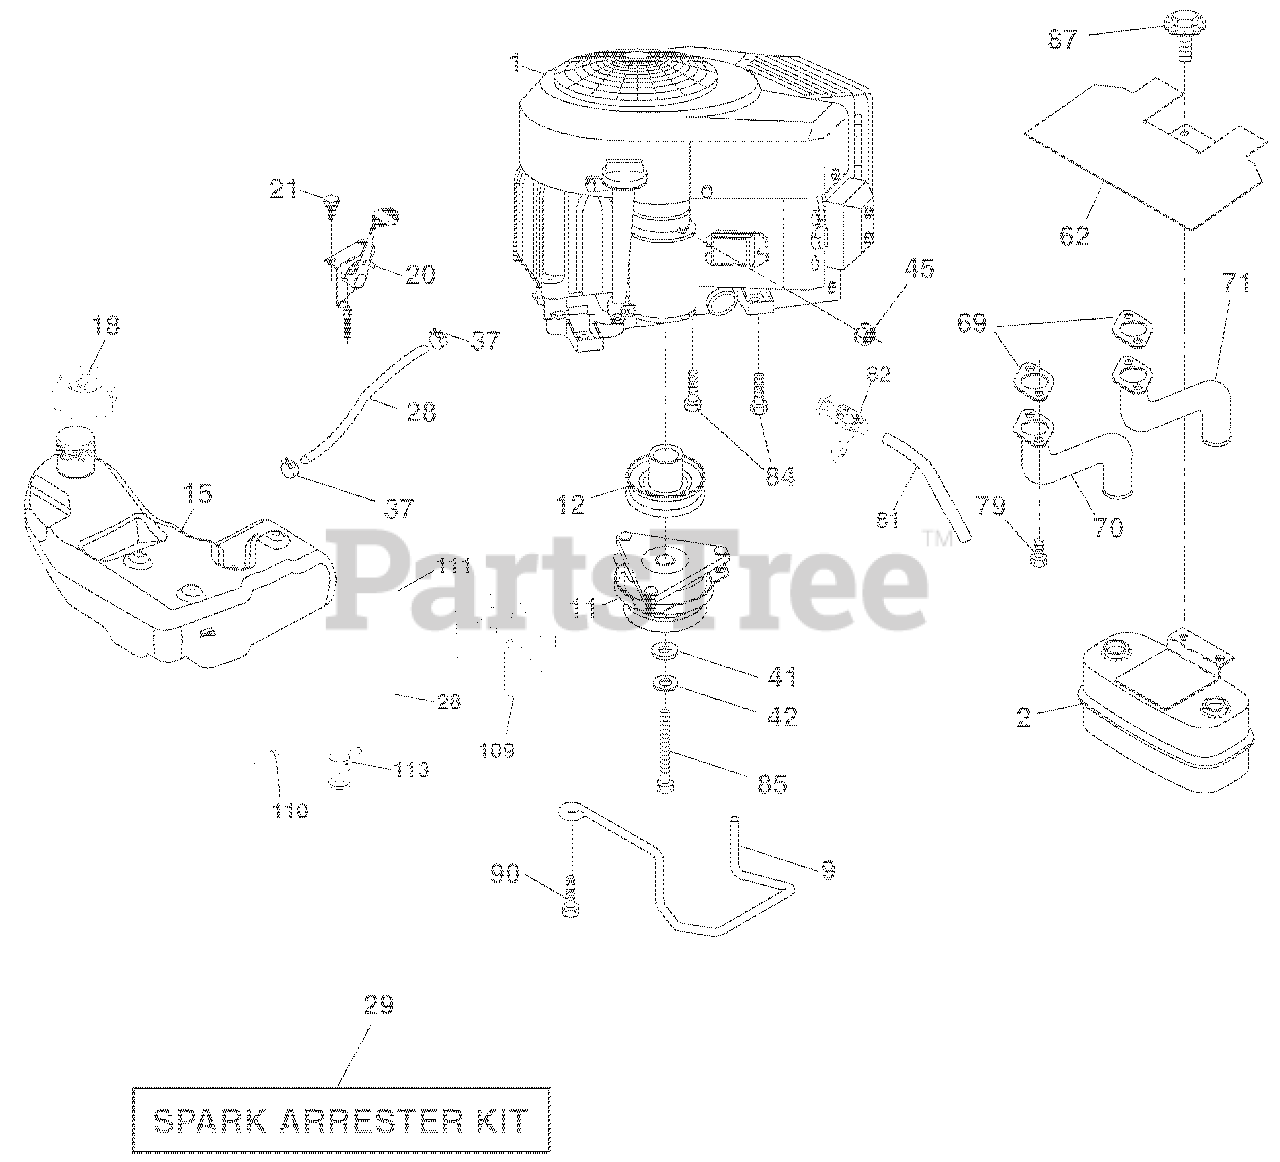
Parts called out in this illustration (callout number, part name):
1	ENGINE BRIGGS 407777-1569-G1
2	MUFFLER ASM.TWIN.LO-TONE
9	KEEPER.BELT.ENGINE.4.25"NSTG
11	CLUTCH.ELECTRIC.LT.1"CRANK
12	PULLEY.ENGINE.TUFFTORQE.1"CRK.
15	TANK.FUEL.ASM.3.00 GA.
18	CAP FUEL
20	CONTROL THROTTLE/CHOKE
28	LINE.FUEL.64"REAR.EMIS.CA.LP
29	KIT.SPARK ARRESTOR(392390 B&S)
37	CLAMP.HOSE.BLK.
41	WASHER.1-1/2 ODX15/32 IDX.250
42	WASHER.LOCK.HVY HLCL.SPR.7/16
45	Nut, Keps Hex 1/4-20 unc
62	SHIELD.HEAT.MUFFLER.
69	GASKET MUFFLER
70	EXHAUST TUBE LH
71	EXHAUST TUBE RH
79	SCREW SOCKET HEAD 5/16-18 X 1
81	TUBE.DRAIN.OIL.EASY
82	VALVE OIL DRAIN
84	Screw 3/8-16 x <
85	BOLT.HEX.7/16-20X4XGR5-1.5THR.
87	BOLT.5/16-18 UNC X 1 W/SEMS.BL
90	SCREW.3/8-16X1.SMGML.TAP/R.BLK
109	CANISTER.CARBON.FILTER ASM.TEX
110	VALVE.ASM.ANTI-SLOSH
111	PURGE LINE
113	VALVE.SLANT.CARTIDGE
